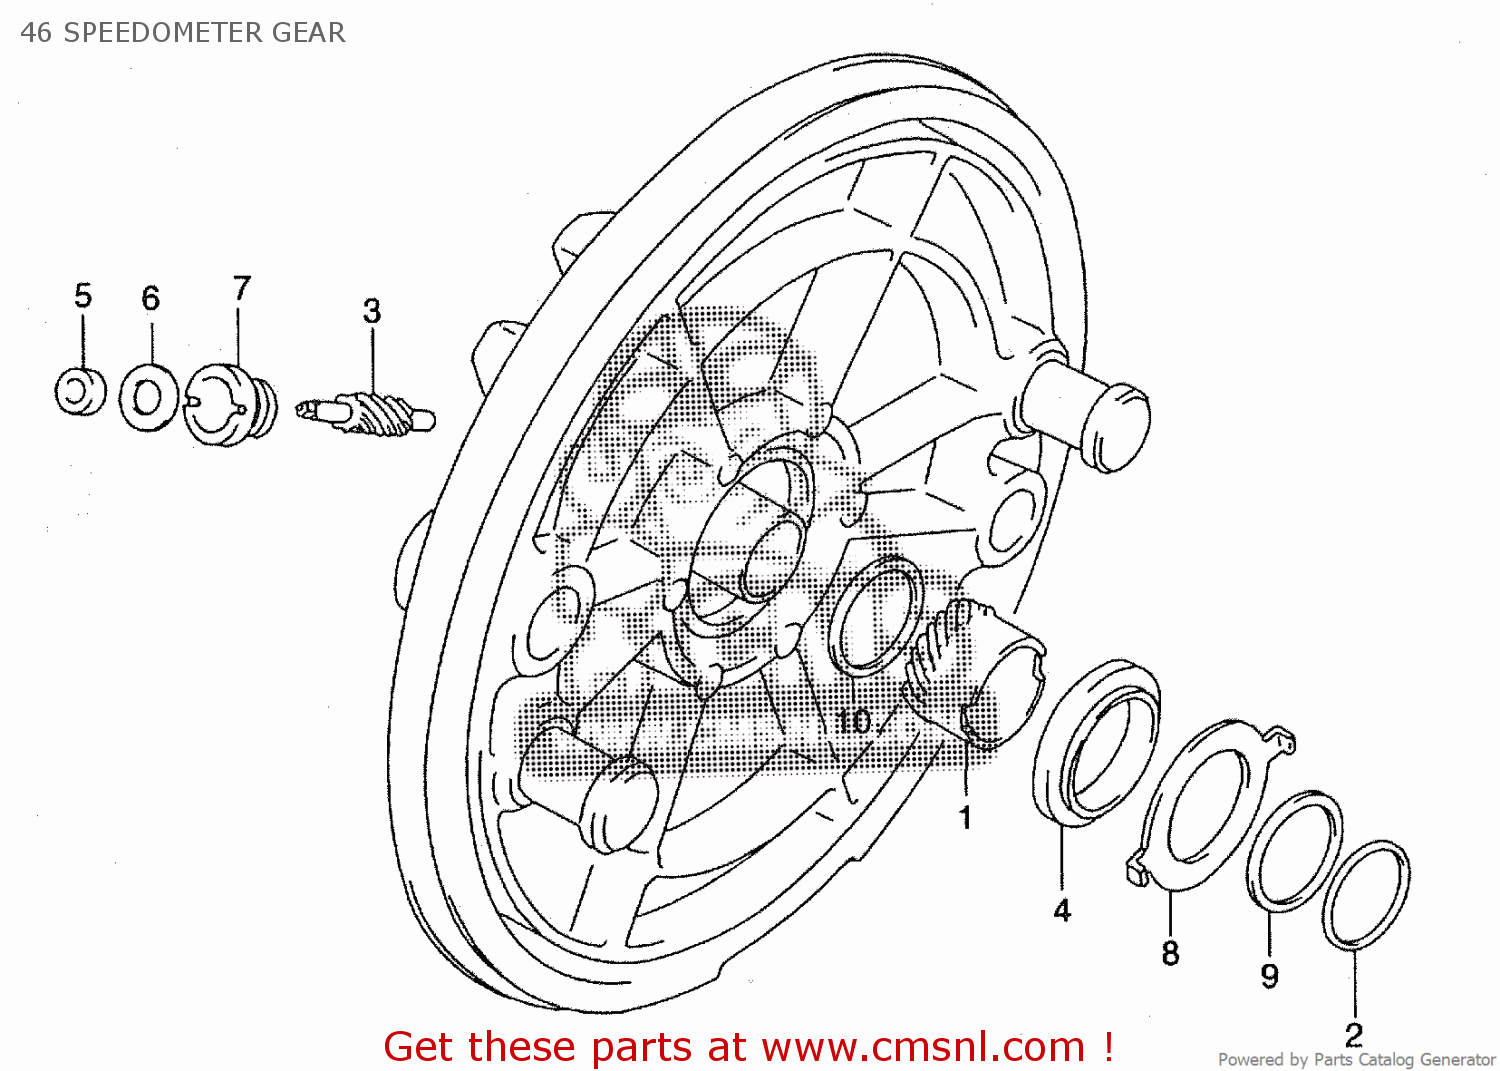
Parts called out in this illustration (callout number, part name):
1	GEAR,SPEEDOMETER (NT:25)
2	RING,SNAP
3	PINION, SPEEDOMETER
4	SEAL,OIL(26X38X4)
5	SEAL,OIL(6X15X3)
6	WASHER(6.2X9X0.3)
7	BUSH,SPEEDOMETER PINION
8	DRIVER, SPEEDOMETER GEAR
9	WASHER(22.5X27X1)
10	SHIM(22X28X1)
